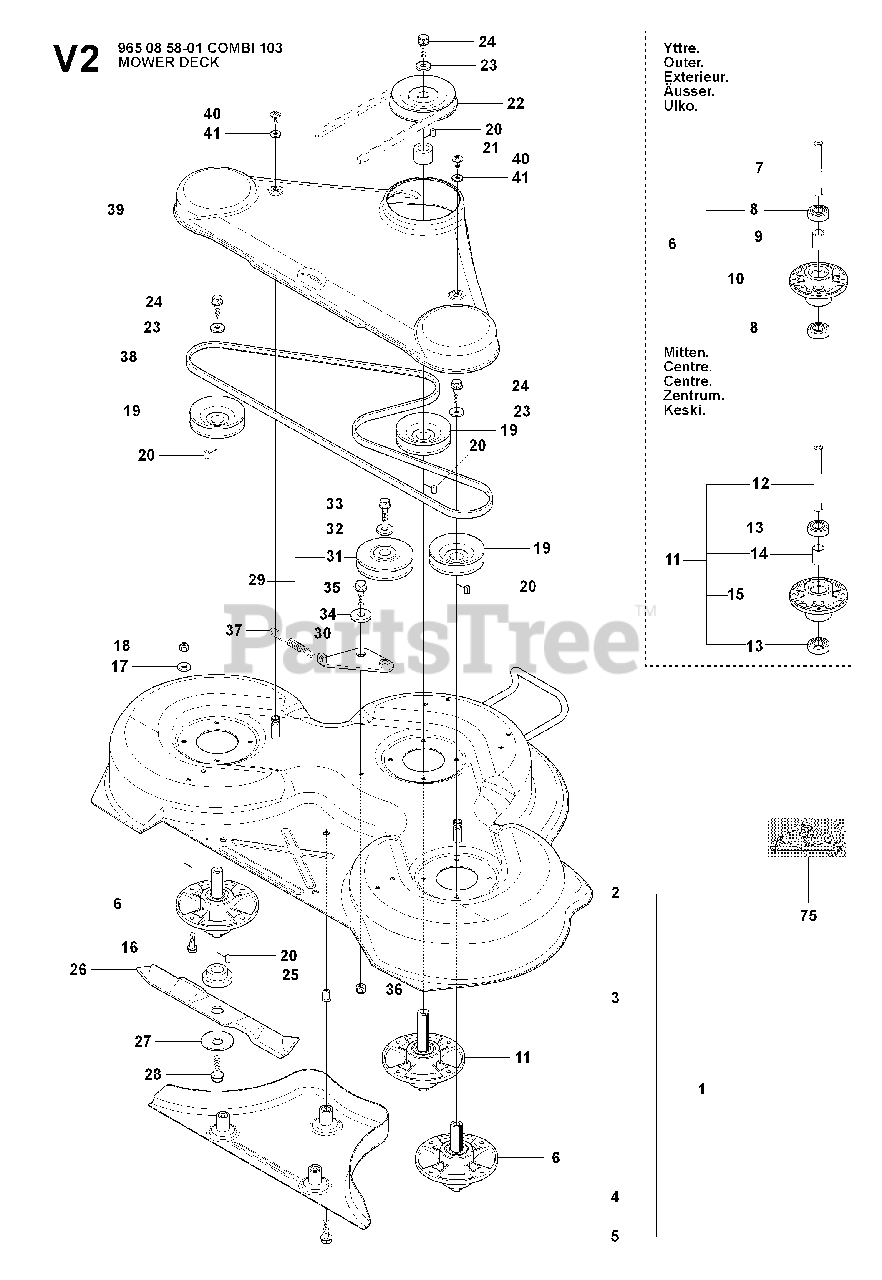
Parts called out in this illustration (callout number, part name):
6	RP SPINDLE ASSY
10	BEARING HOUSING
11	RP SPINDLE ASSY
15	BEARING HOUSING
17	WASHER BRB 8.4X17
18	LOCKNUT M8
26	BLADE
29	BELT TENSIONER ASSY
30	BELT TENSIONING ARM
34	WASHER
36	LOCKNUT M8
38	BELT
